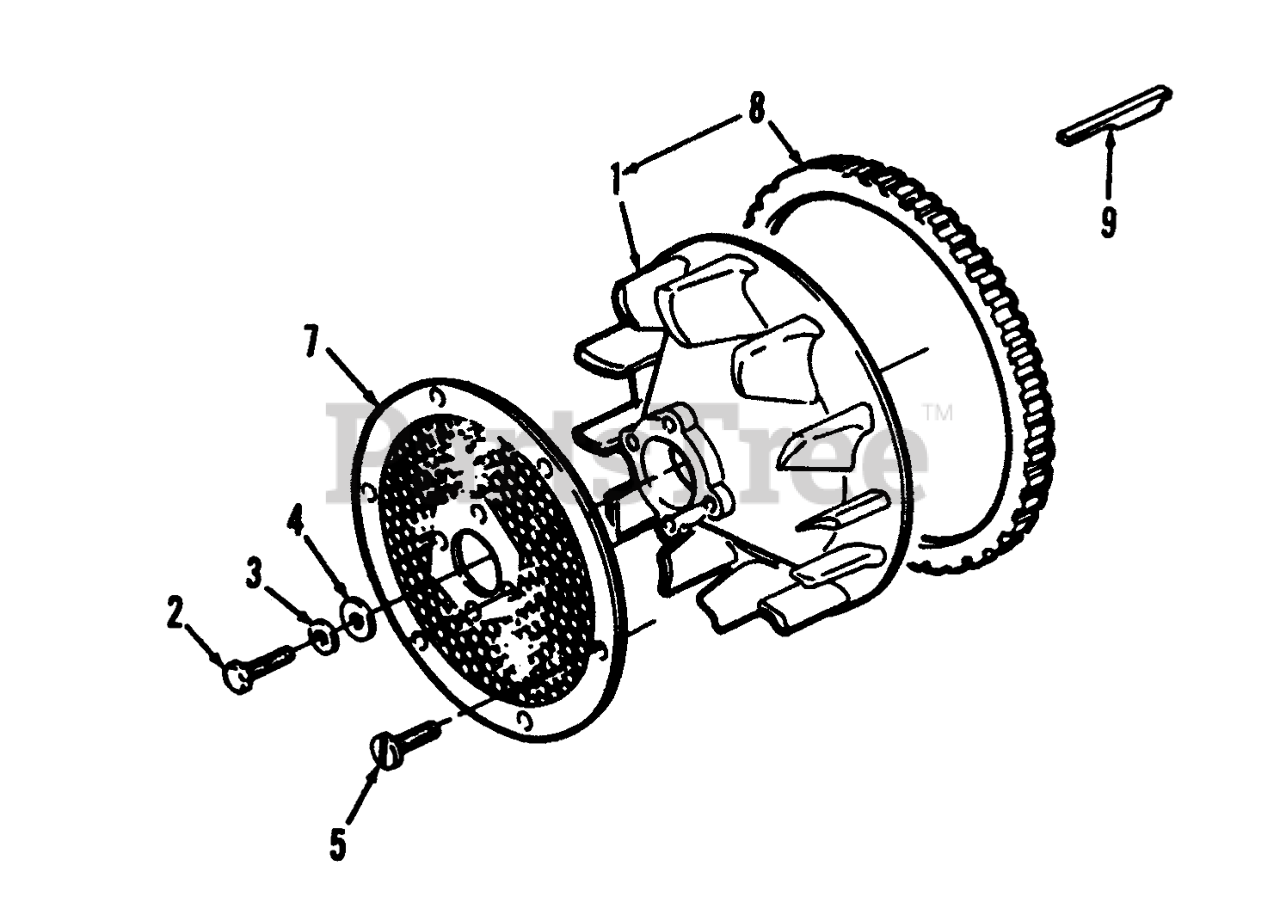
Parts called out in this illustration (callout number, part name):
1	Flywheel (Includes Ring Gear)
2	Screw
3	WASHER-FLAT
4	WASHER-FLAT
5	Bolt
7	Screen
8	Gear-Ring
9	Key
